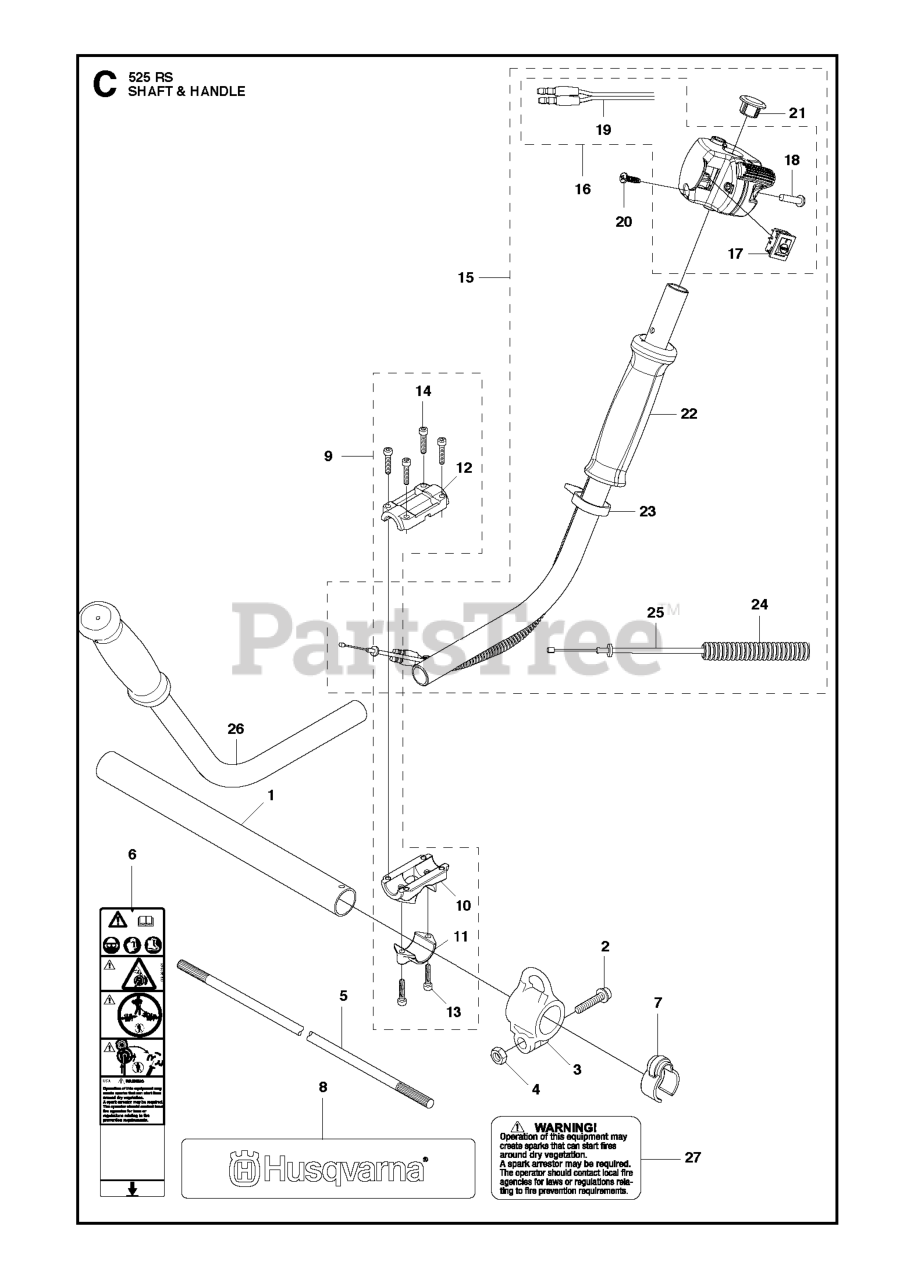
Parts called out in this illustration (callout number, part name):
2	SCREW
3	HARNESS HOLDER
5	DRIVESHAFT
6	LABEL WARNING TRIMMERS AND BRU
9	BRACKET ASSY.
13	BOLT
17	STOP SWITCH NM_09091801
27	DECAL SPARK ARRESTOR WARNING
